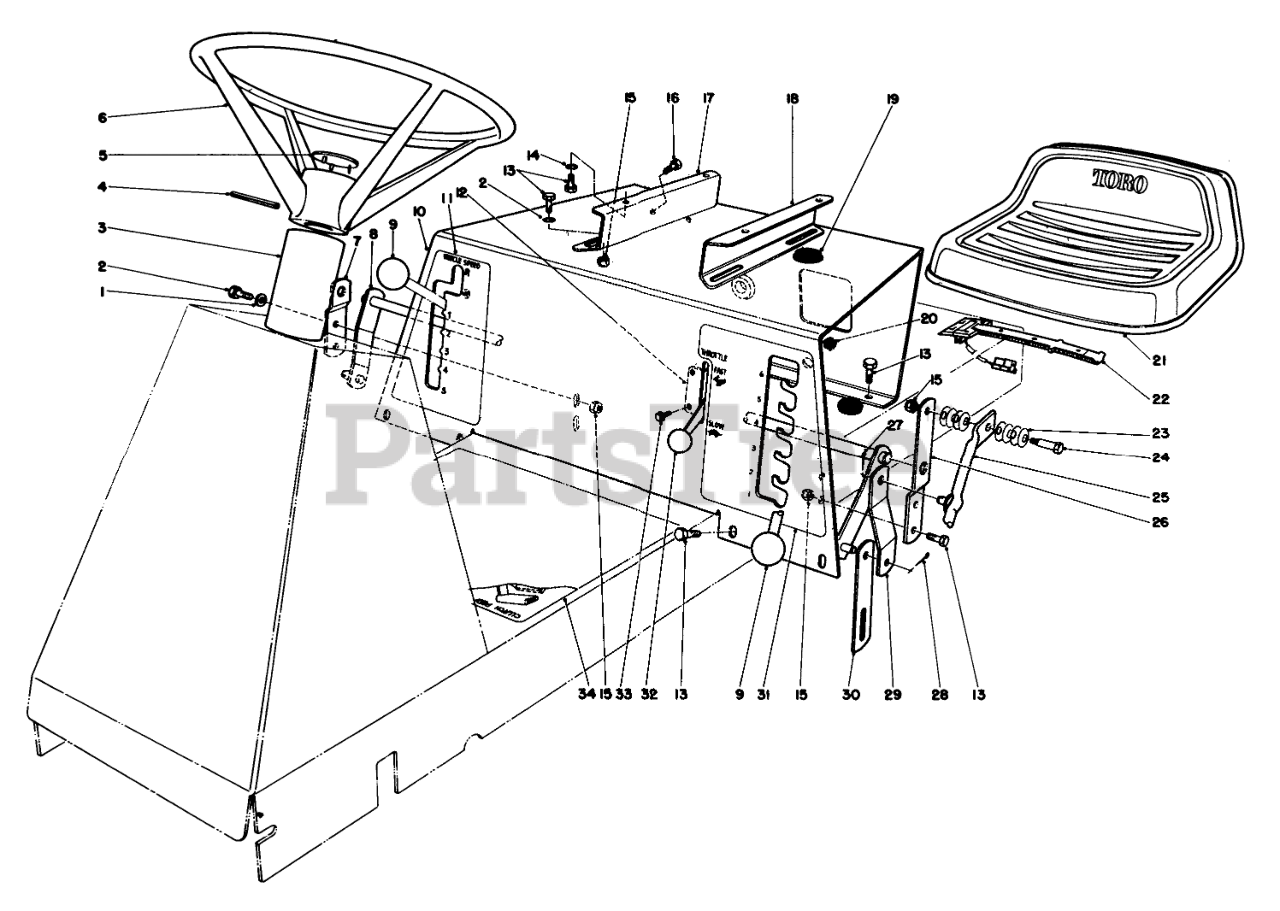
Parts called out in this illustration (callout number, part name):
1	WASHER-PLAIN
2	SCREW-HH
3	STRG. SHAFT COVER
4	PIN-ROLL
5	Cap-Steering Wheel
6	Wheel-Steering (Incl. Ref. #5)
7	Bracket H.O.C. Support
8	Hose Pump #1
10	RETAINER-DRAWBAR
11	Screen
12	Throttle Control (Incl. Ref. #32)
13	SCREW-HH
14	WASHER-LOCK
15	NUT-LOCK, NI
16	SCREW-HH
17	Shaft-Stub Axle
18	Bracket-Seat RH.
19	GROMMET
20	GROMMET
21	Seat
22	SWITCH-SEAT
23	WASHER-BELLEVILLE
24	BOLT-SHOULDER
25	HOC LEVER WA B
26	Bracket
27	PIN-COTTER
28	PIN-COTTER
29	Bracket-Height Of Cut Engagement
30	Link-Deck Suspension
31	Decal-Height Of Cut
32	KNOB-CONTROL
33	SCREW-HWHTF
34	Decal-Instructions
